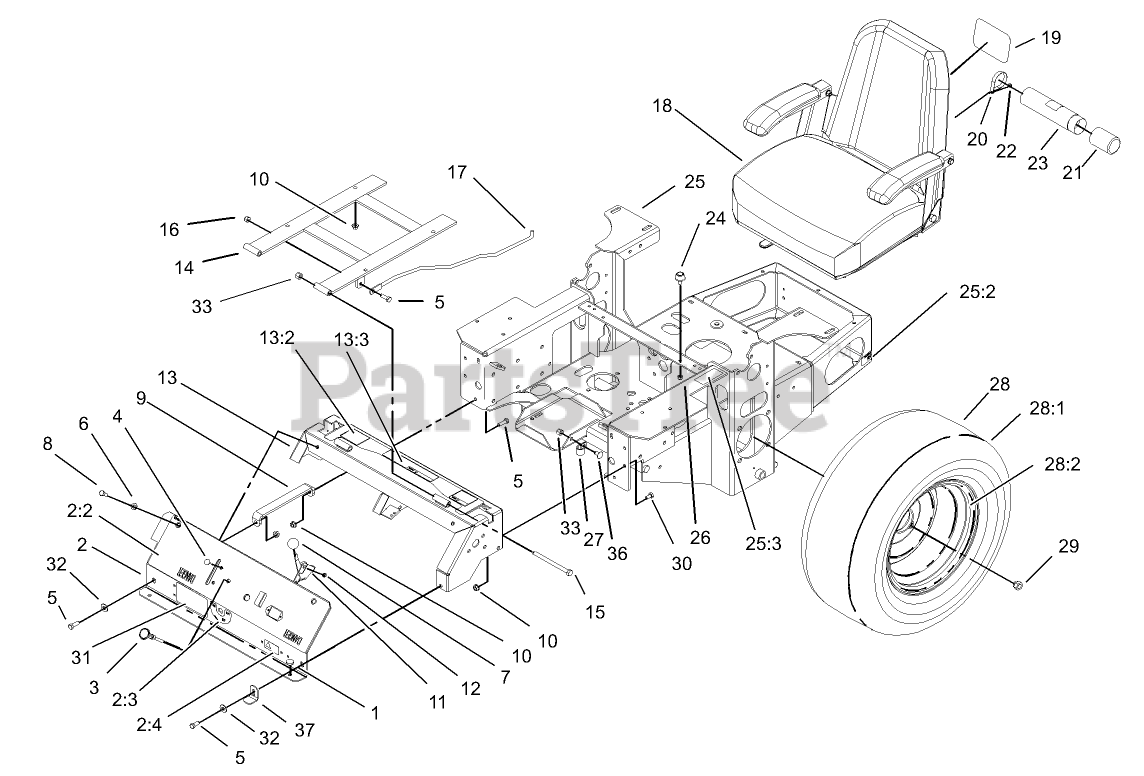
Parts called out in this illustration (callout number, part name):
1	BUMPER
2	Console ASM
2:2	DECAL-PANEL, CONTROL
2:3	DECAL-VALVE, FUEL
2:4	DECAL-PROTECTION, EAR
3	CONTROL-CHOKE
4	BOLT-CARR
5	SCREW-HH
6	WASHER-PLAIN
7	KNOB-BALL
8	SCREW-HH
9	BRACKET
10	NUT-HF
11	THROTTLE CABLE ASM
12	NUT-LOCK, NI
13	CONSOLE
13:2	DECAL-CONTROL, MOTION
13:3	DECAL-BATTERY
14	FRAME-SEAT
15	SCREW-HH
16	NUT-LOCK, NI
17	ROD-RETAINER, SEAT
18	SEAT ASM
19	DECAL
20	CLAMP-R
21	CAP-HOUSING
22	SCREW-HWHTF
23	TUBE-MANUAL
24	BUMPER
25	Main Frame ASM
25:2	DECAL-SURFACE, HOT
25:3	Decal-Release, Drive
26	NUT-LOCK, NI
27	CLIP-LOOM
28	WHEEL AND TIRE ASM
28:1	TIRE
29	NUT-LUG
30	SCREW-HH
31	DECAL-Z147
32	WASHER-FLAT
33	NUT-LOCK, NI
36	SCREW-CARR
37	STOP-COVER
